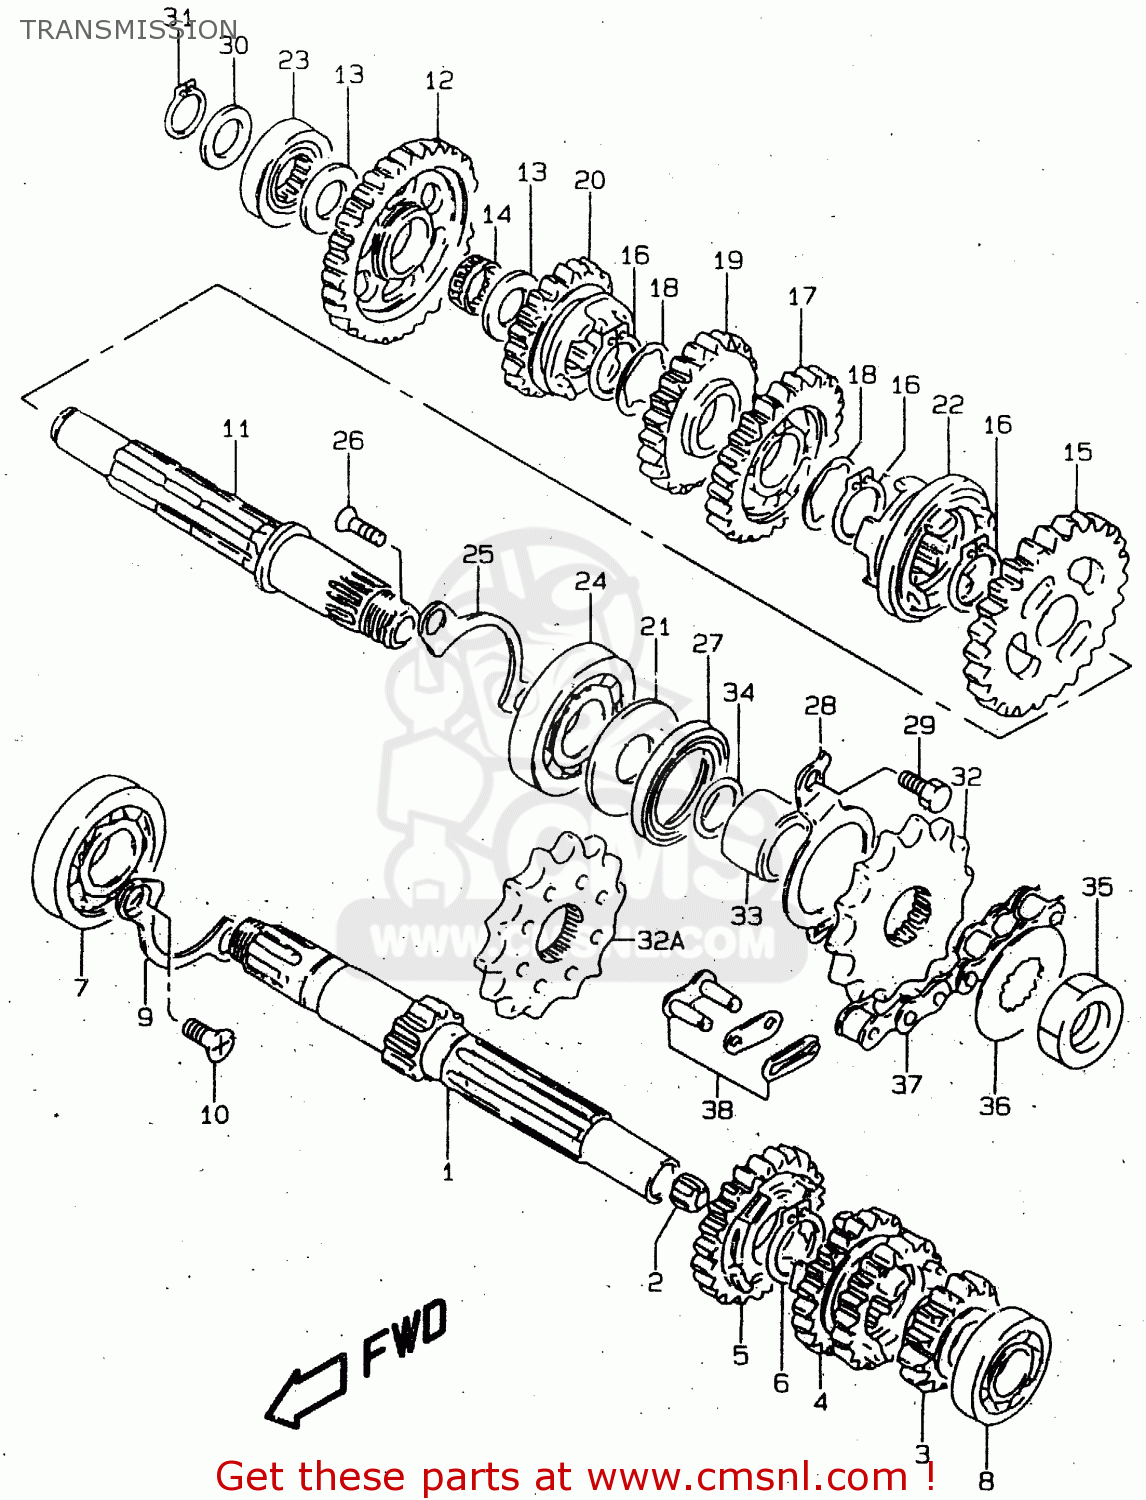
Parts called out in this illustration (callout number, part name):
1	SHAFT,COUNTER (NT:11)
2	BUSH
3	GEAR,2ND DRIVE(NT:14)
4	GEAR,3RD & 4TH DRIVEN(NT:19/21
5	GEAR,FIFTH DRIVE (NT:23)
6	CIRCLIP
7	BEARING(20X47X14)
8	BEARING
9	RETAINER,DRIVE SHAFT BEARING
10	SCREW
11	SHAFT,DRIVE
12	GEAR,FIRST DRIVEN (NT:33)
13	WASHER
14	BEARING(15X19X7.8)
15	GEAR,2ND DRIVEN(NT:26)
16	CIRCLIP
17	GEAR,3RD DRIVEN(NT:26)
18	WASHER,LOCK
19	GEAR,FOURTH DRIVEN
20	GEAR,FIFTH DRIVEN
21	WASHER,OIL SEALING
22	WHEEL,SLIDING DOG
23	BEARING(15X33X12)
24	BEARING(20X47X14)
25	RETAINER,DRIVE SHAFT BEARING
26	SCREW
27	SEAL,OIL(27X40X6)
28	PLATE,DRIVESHAFT OIL
29	BOLT
30	SHIM(15X20X1)
31	CIRCLIP
32	SPROCKET,ENGINE
32A	SPROCKET,ENGINE(NT:14)
33	SPACER
34	O RING(D:2.4,ID:19)
35	NUT
36	WASHER
37	CHAIN,DRIVE
38	JOINT(RK)
